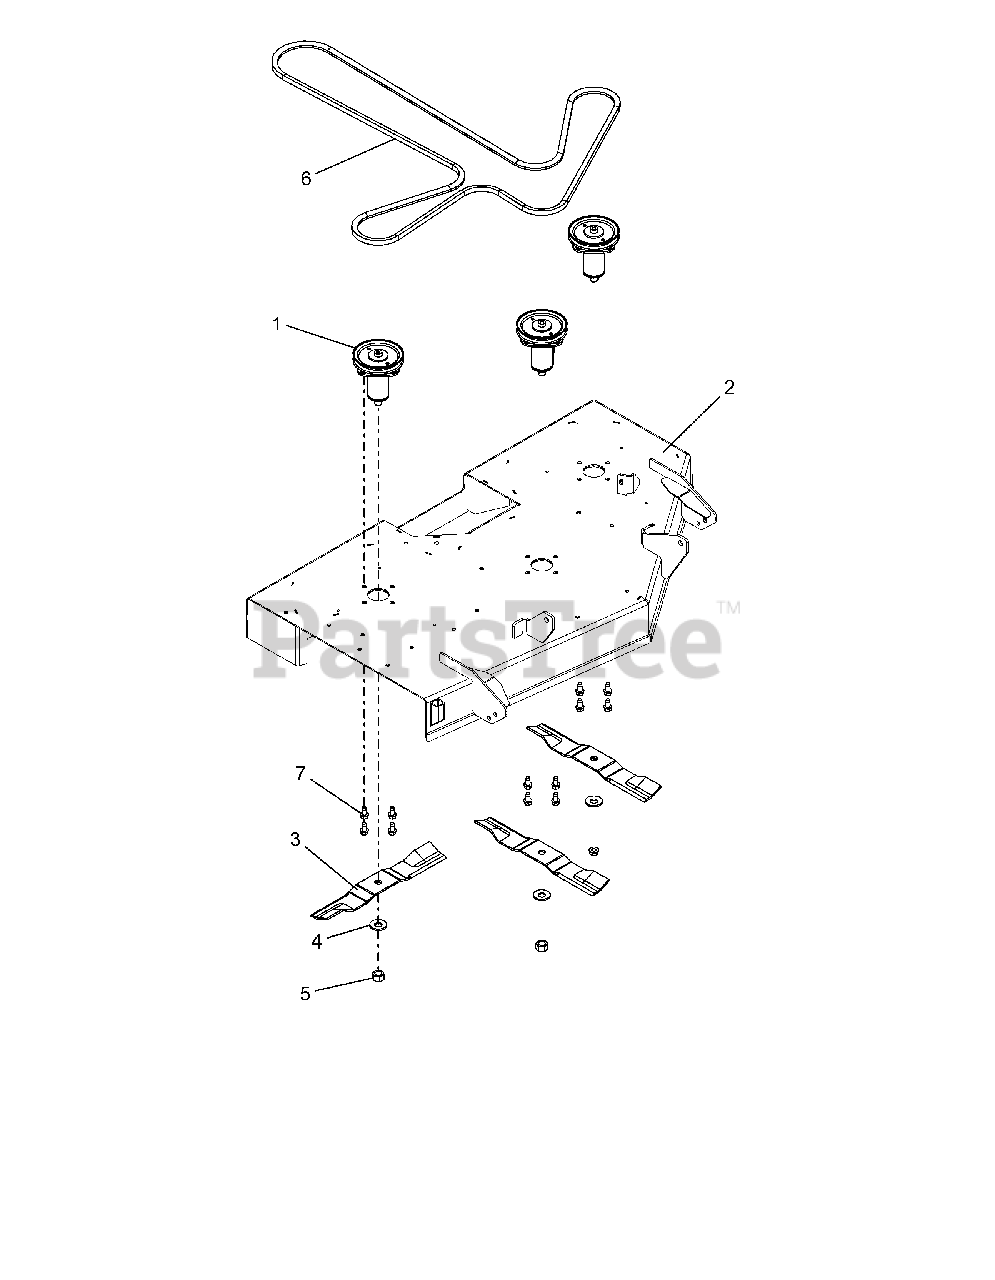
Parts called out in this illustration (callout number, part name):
1	KIT, DECK SPINDLE ASM-IKON-ZTX
2	KIT, 42" GRAVELY DECK W/DECALS
3	BLADE, MOWER 15.00"
4	WSHR-BLVL .669X1.535X.138
5	NUT-STD .625-18 ZCC
6	V-BELT, 4L-WRAPPED
7	SCR,TAP .375-16X.75 HWH TR ZCC
